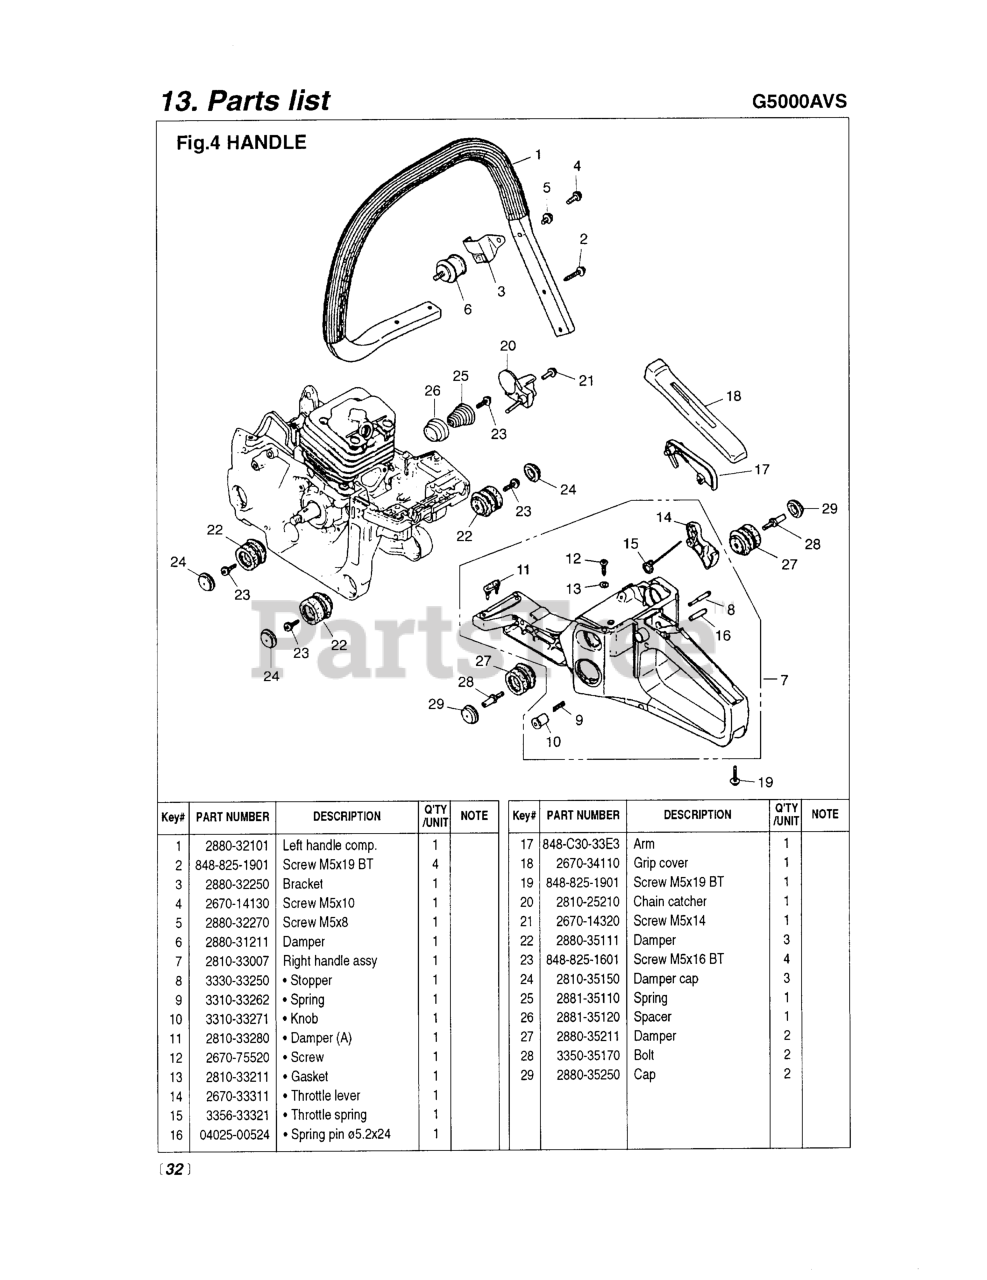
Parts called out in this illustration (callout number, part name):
1	LEFT HANDLE COMPLETE
2	SCREW (RPLS. 2671-32110)
3	BRACKET
4	SCREW
6	DAMPER
7	HANDLE ASSY (RPLS -33004)
8	STOPPER
10	KNOB
11	DAMPER (REPLACES 3356-33281)
14	LEVER (RPLS-33310)
15	SPRING
17	ARM (REPLACES 3356-33352)
18	COVER, GRIP
19	SCREW (RPLS. 2671-32110)
20	CATCHER, CHAIN (RPL 2670-25212
21	SCREW (REPLACES 2616-24320)
22	DAMPER
23	SCREW
25	SPRING
26	SPACER
27	DAMPER
29	CAP
